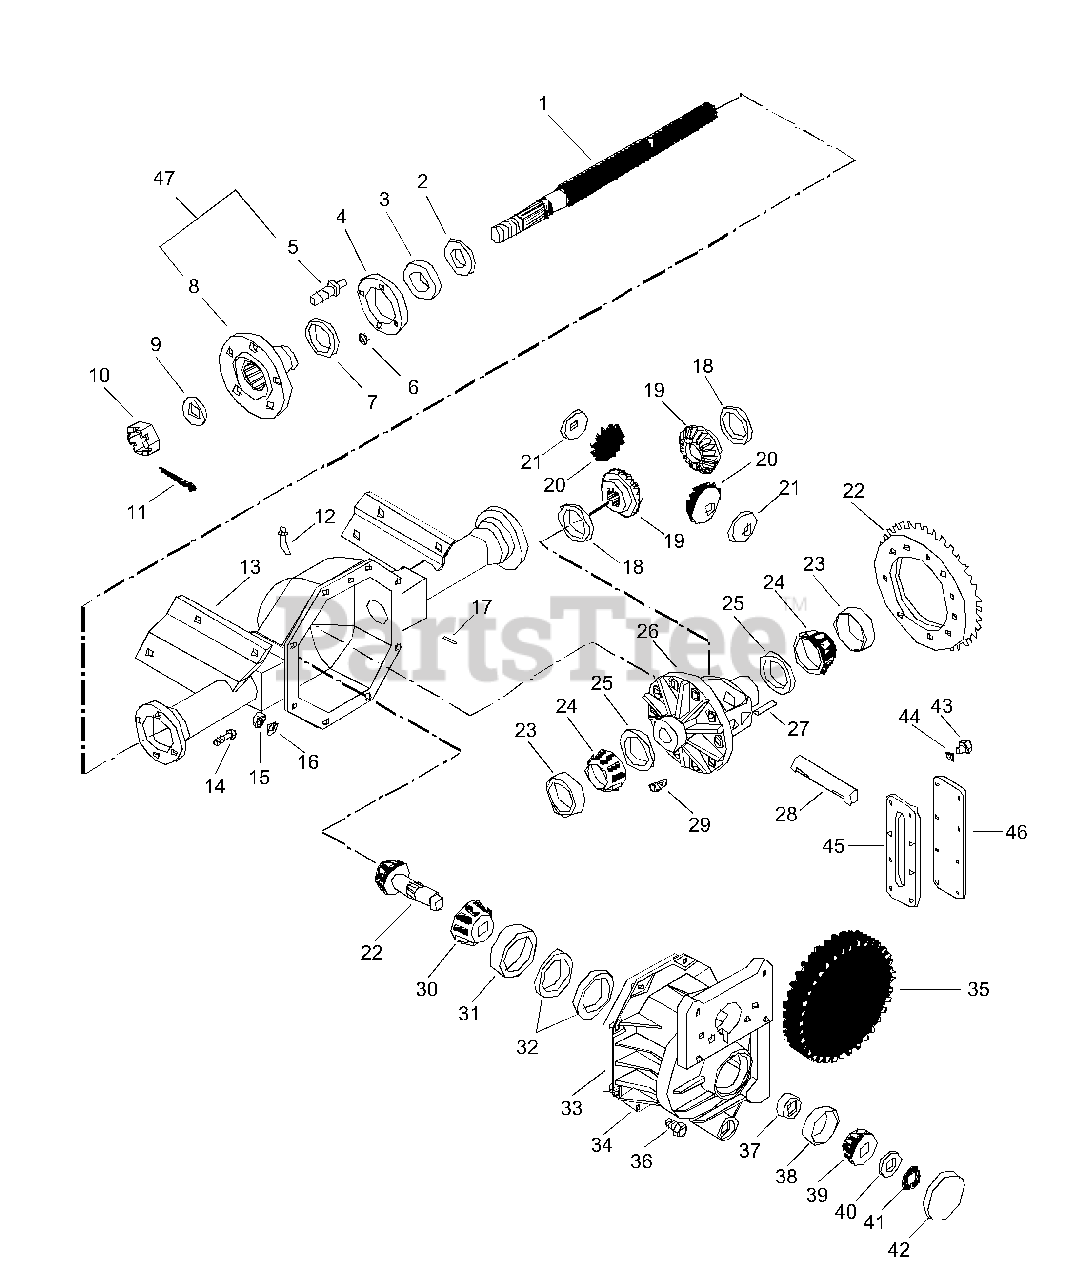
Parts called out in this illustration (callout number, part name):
1	Axle Shaft Left Hand
1	Axle Shaft Right Hand
2	Seal 1.183 x 1.183 x .265
3	Bearing-Cone 46MM x 17MM
4	Gasket-Wheel Bearing
5	Carrier Lug Bolt
6	Nut-Locking-Flange .312-24
7	Felt Seal
8	Axle Flange
9	Washer-Flat-Steel .875 x 1.500 x .1196
10	Nut-Slotted .875-14
11	Pin-Cotter .15 x 1.50
12	Vent
13	Lower Housing
14	Bolt-Hex .31-24 x 1.25 Grade 8
15	Nut-Hex .312-18 Grade 2
16	Washer-Lock Internal .313 x .030
17	Dowel Pin
18	Washer-Flat-Steel 1.578 x 2.375 x .031
19	Side Gear
20	Bevel Gear
21	Washer-Bellville .703 x 1.593 x .031
22	Pinion & Gear
23	Bearing-Cup 2.892 x .580
24	Bearing-Cone 1.63 x .78
25	Shim
26	Differential Case
27	Lock Pin
28	Pinion Shaft
29	Bolt .38-24 x .812
30	Bearing-Cone 1.188 x .84
31	Bearing-Cup 2.253 x .656
32	Shim
33	Gasket
34	Front Housing w/Bearing Cap & Screw
35	Spur Gear
36	Bolt-Hex .31-18 x 1.00 Grade 5
37	Front Pinion Bearing Spacer
38	Bearing-Cup 1.968 x .550
39	Bearing-Cone .844 x .72
40	Shim Assembly
41	Ring-Retaining-External .813 x .042
42	Cup Plug
43	Screw-Tapping 5HX-0.8 x 16MM
44	Washer-Lock External 12 x .025
45	Gasket
46	Side Cover
47	Axle Flange Assembly
